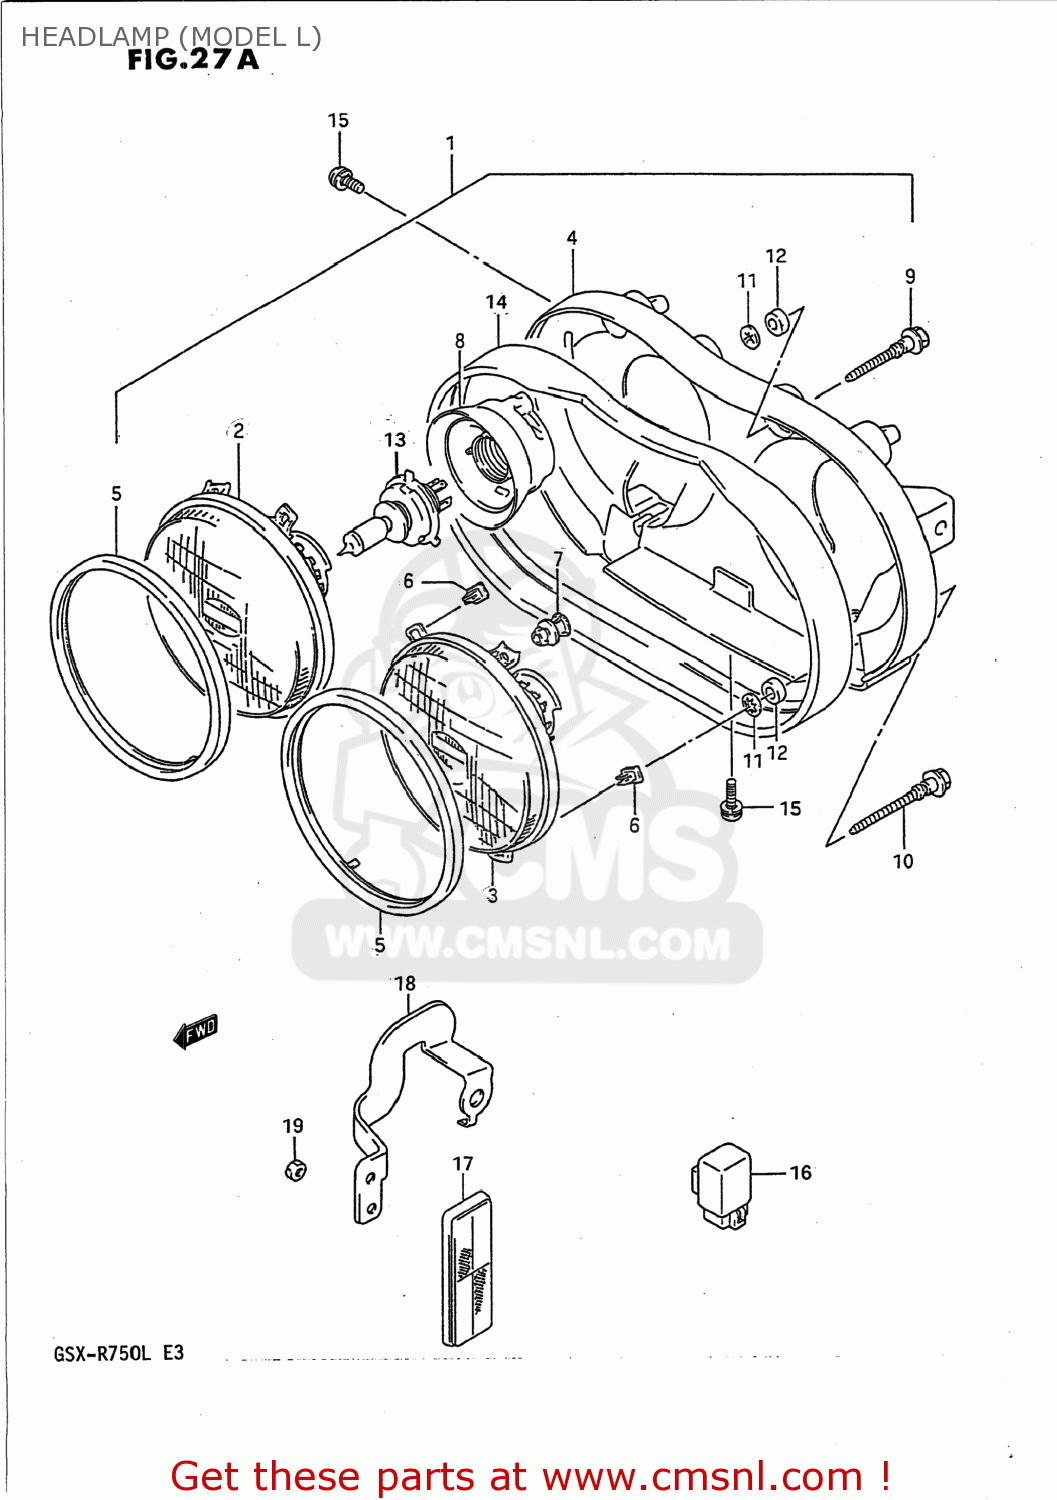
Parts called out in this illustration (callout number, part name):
1	HEADLAMP ASSEMBLY
2	LAMP UNIT,L
3	LAMP UNIT,R
4	HOUSING,HEAD LAMP
5	RING,RETAINING
6	NUT,HEADLAMP ADJUSTER
7	SCREW,SPHERICAL
8	COVER,SOCKET
9	SCREW,HEADLAMP ADJUST
10	SCREW,ADJUSTER
11	WASHER
12	BUSHING
13	BULB(12V60/55W,H4)
14	GASKET,HEADLAMP
15	SCREW
16	RELAY ASSY,HEADLAMP
17	REFLEX REFLECTOR,FR SIDE
18	BRACKET,FR SIDE REFLECTOR,R
19	NUT
